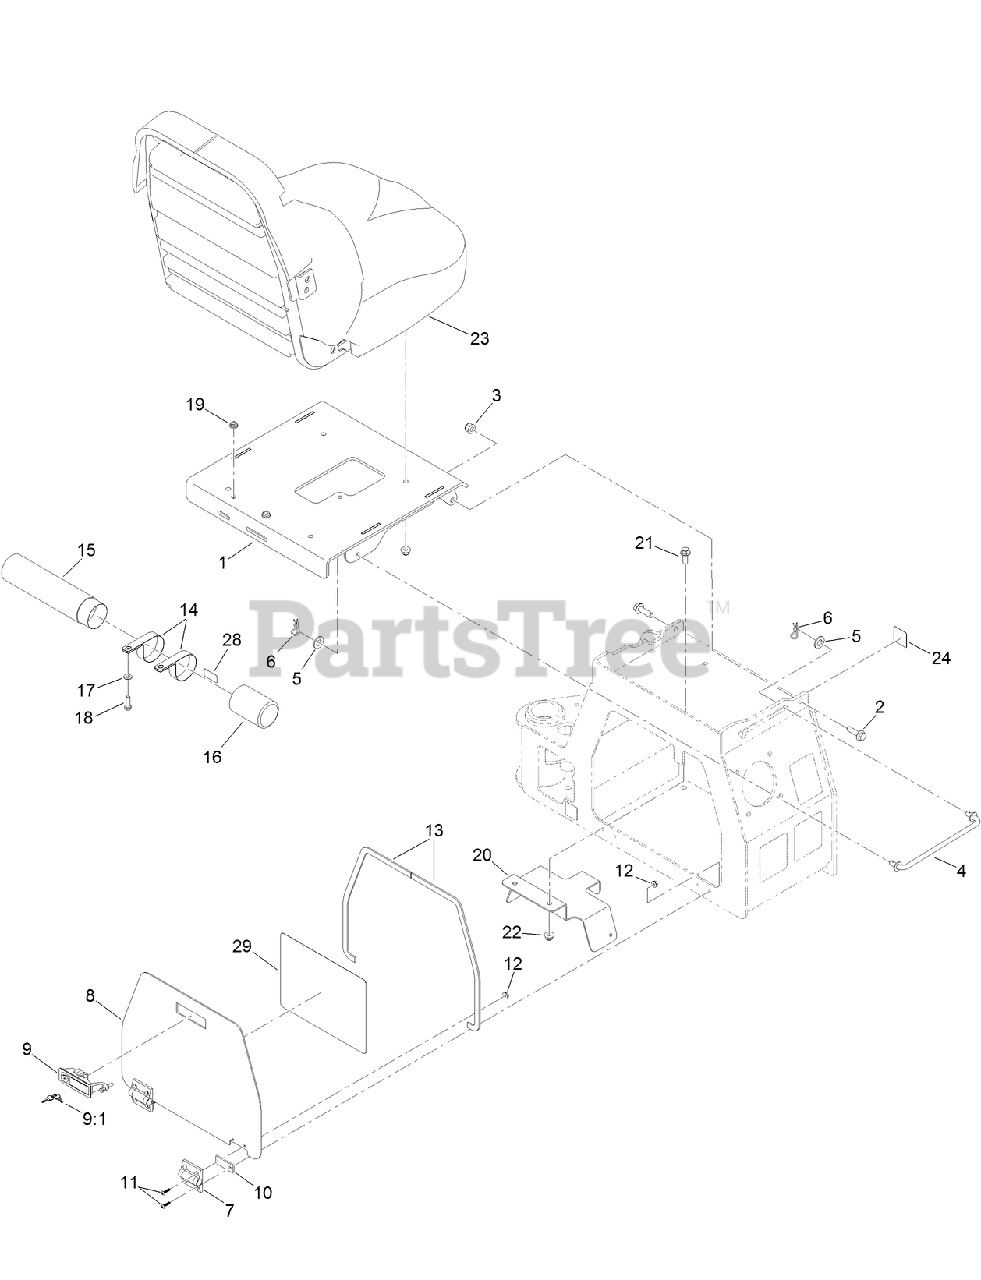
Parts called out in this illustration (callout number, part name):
1	BASE-SEAT
2	SCREW-HHF
3	NUT-LOCK, NI
4	ROD-PROP, SEAT
5	WASHER-HARDENED
6	PIN-HAIR
8	DOOR-STORAGE, CONSOLE
9	LATCH-TRIGGER, RAISED (W/LOCK)
10	SPACER-HINGE
11	SCREW-PRH
12	NUT-KEPS
13	FOAM-RADIATOR
14	CLAMP-R
15	TUBE-MANUAL
16	CAP-HOUSING
17	WASHER-PLAIN
18	SCREW-HH
19	NUT-HF
20	BRACKET-MOUNTING, HARNESS
21	SCREW-HHF
22	NUT-HF, NI
24	DECAL-SEAT SLIDE
28	PRODUCTION YEAR DECAL PHANTOM
29	DECAL-SERVICE
